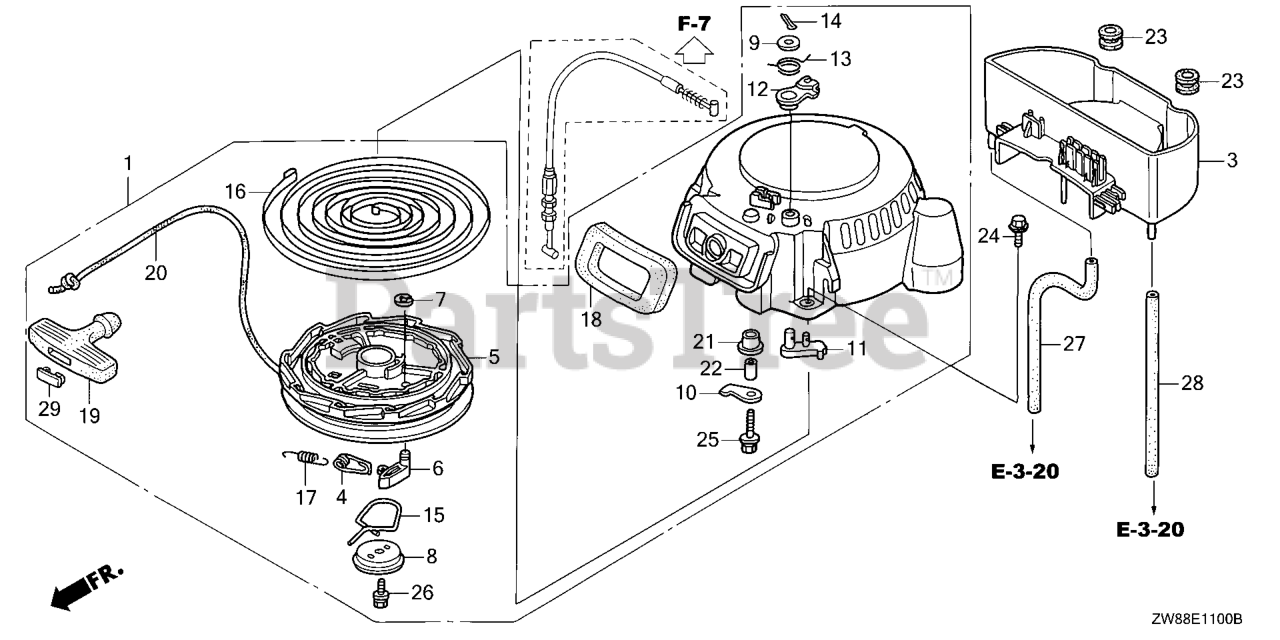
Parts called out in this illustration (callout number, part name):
1	STARTER ASSY., RECOIL
2	CASE, RECOIL STARTER
3	CASE B, STARTER (PT)
4	GUIDE, RECOIL STARTER
5	REEL, RECOIL STARTER
6	RATCHET SET, STARTER
6	RATCHET, STARTER
7	RATCHET SET, STARTER
7	E-RING
8	PLATE, FRICTION
10	WASHER, THRUST
11	STOPPER, REEL
12	ARM, STOPPER
13	SPRING, STOPPER
14	PIN, SPLIT
15	SPRING, FRICTION
16	SPRING, RECOIL STARTER
17	SPRING, RETURN
18	SEAL, RECOIL
19	GRIP, STARTER
20	ROPE, RECOIL STARTER (#5X73") (N/A: USE P/N 08550-ZG921-11)
21	ROLLER, STARTER
22	GUIDE, ROLLER
23	GROMMET, ENGINE COVER
24	BOLT, FLANGE (6X22)
25	BOLT, HEX. (6X25)
26	BOLT, HEX. (6X14)
27	TUBE, WATER DRAIN
28	BULK HOSE, VACUUM (8X1000) (Honda Code 5339163). (8X100)
29	CAP, STARTER KNOB
